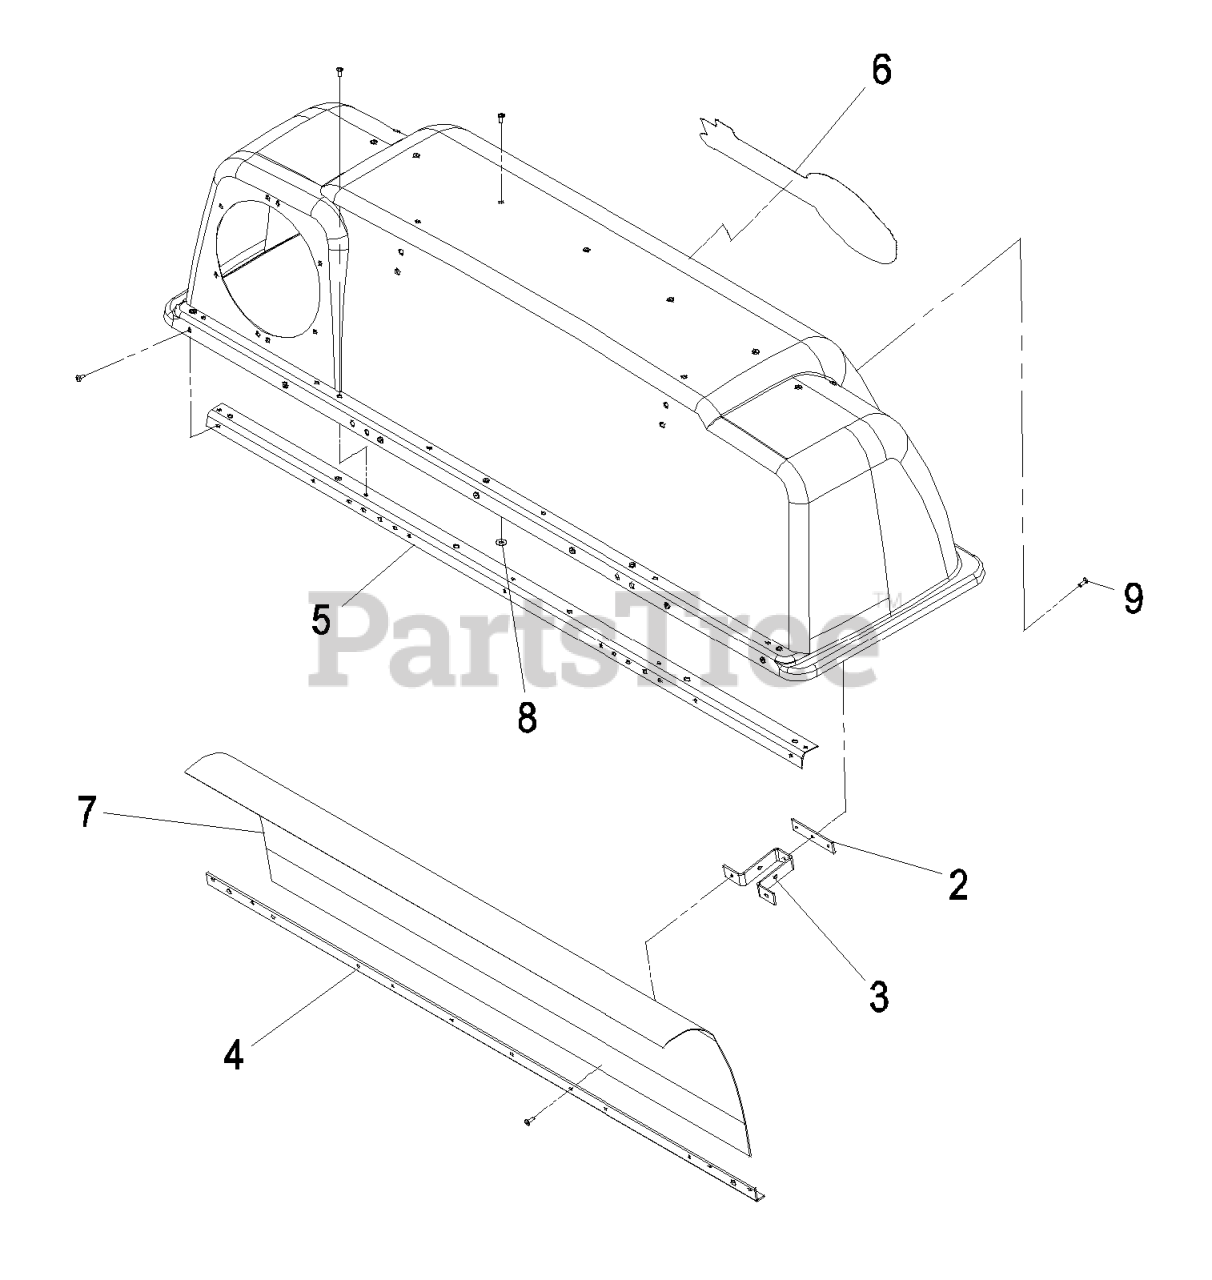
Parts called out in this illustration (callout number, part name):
2	PLATE-LATCH, REINFORCEMEN
3	BRACKET-MOUNT
4	SUPPORT-SCREEN
5	STIFFENER-BAGGER, TOP
6	DECAL, EXMARK
7	SCREEN-BAGGER
8	WASHER-FLAT
9	RIVET-BLIND
